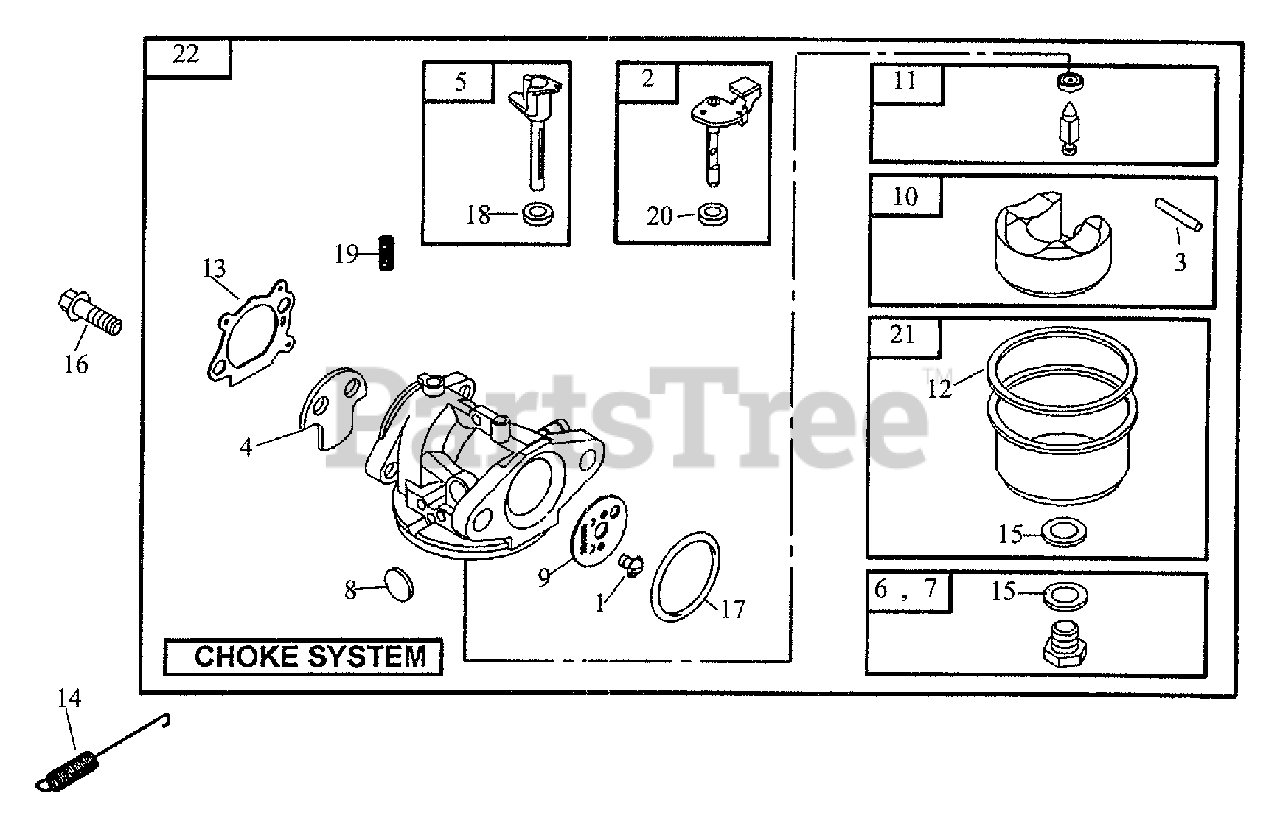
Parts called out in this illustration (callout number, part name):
1	Screw, Throttle Valve
2	Shaft, Throttle
3	Pin, Float Hinge
4	Valve, Choke
5	Shaft, Choke
6	Jet, Main Standard
7	Jet, Main High Alt.
8	Plug, Welch
9	Valve, Throttle
10	Float, Carburetor
11	Kit, Needle & Seat
12	Gasket, Float Bowl
13	Gaske, Air Cleaner
14	Spring, Return
15	Washer, Seal
16	Screw
17	Seal- Oring, Intake
18	Seal, Choke Shaft
19	Spring, Detent
20	Seal Throttle Shaft
21	Bowl, Float
22	Carburetor
